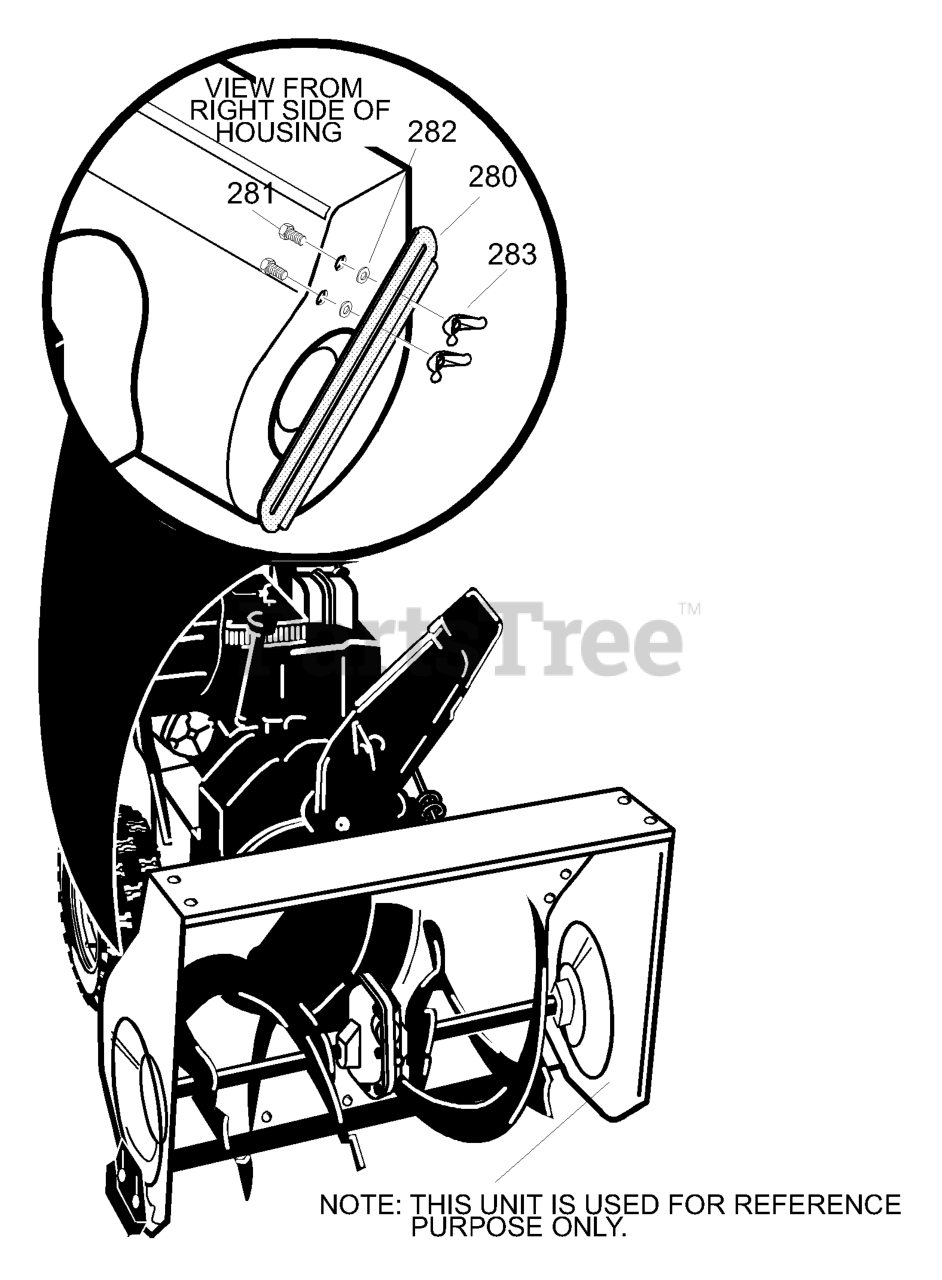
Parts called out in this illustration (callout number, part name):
280	BAR, DRIFT CUTTER
281	BOLT, 5/16-18X0.75
282	WASHER
283	WINGNUT
